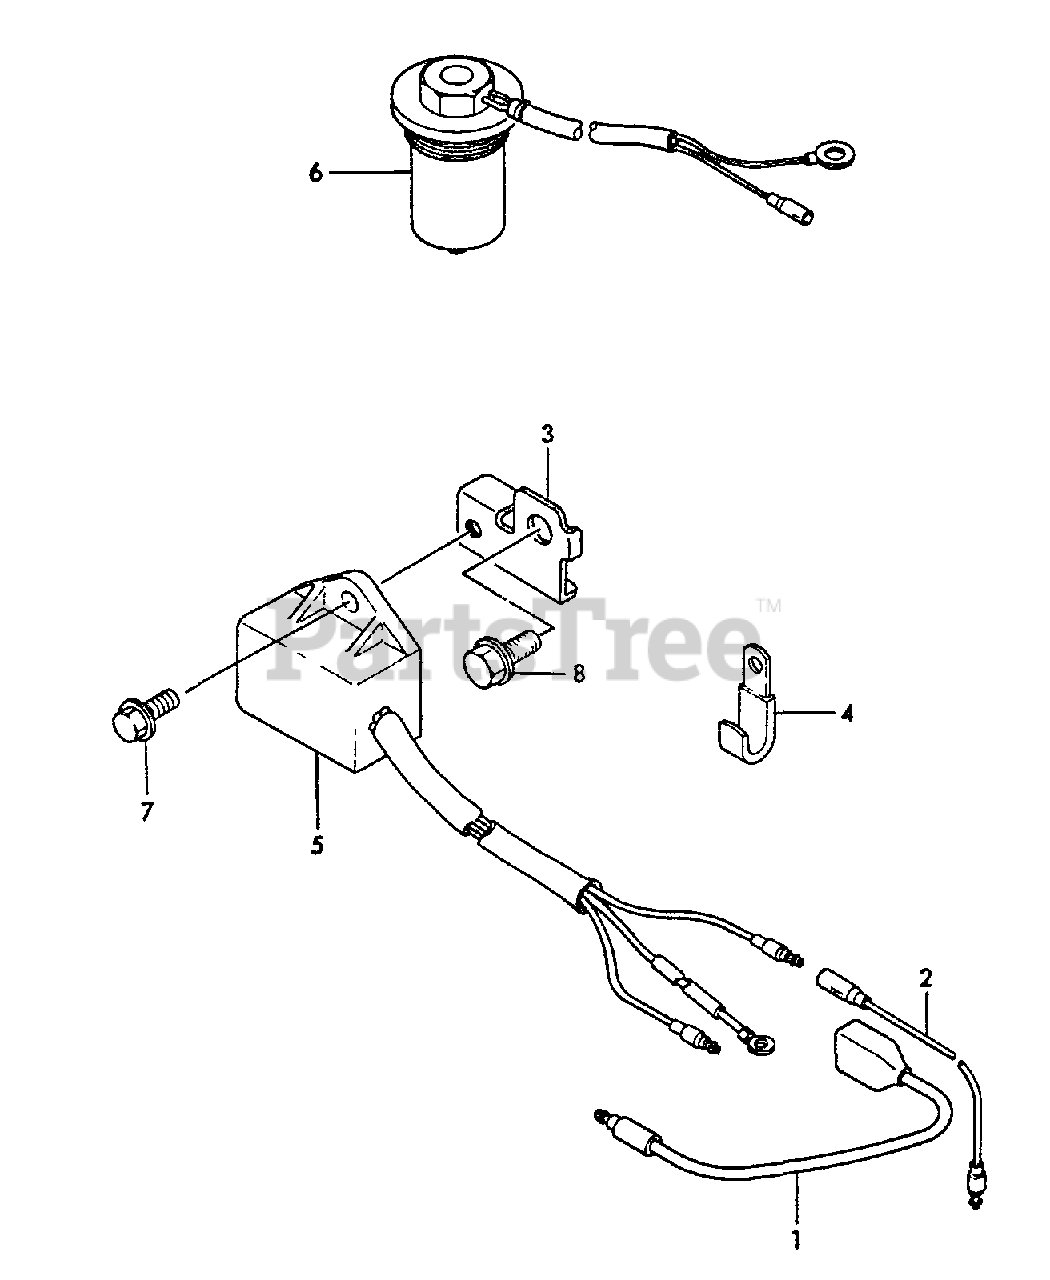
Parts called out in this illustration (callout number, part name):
1	WIRE
2	WIRE
3	STAY, SENSOR UNIT
4	CLAMP
5	SENSOR, OIL
6	SENSOR, OIL LEVEL
7	BOLT - 6X12 -- PLATED
8	BOLT - 8X14 -- PLATED
